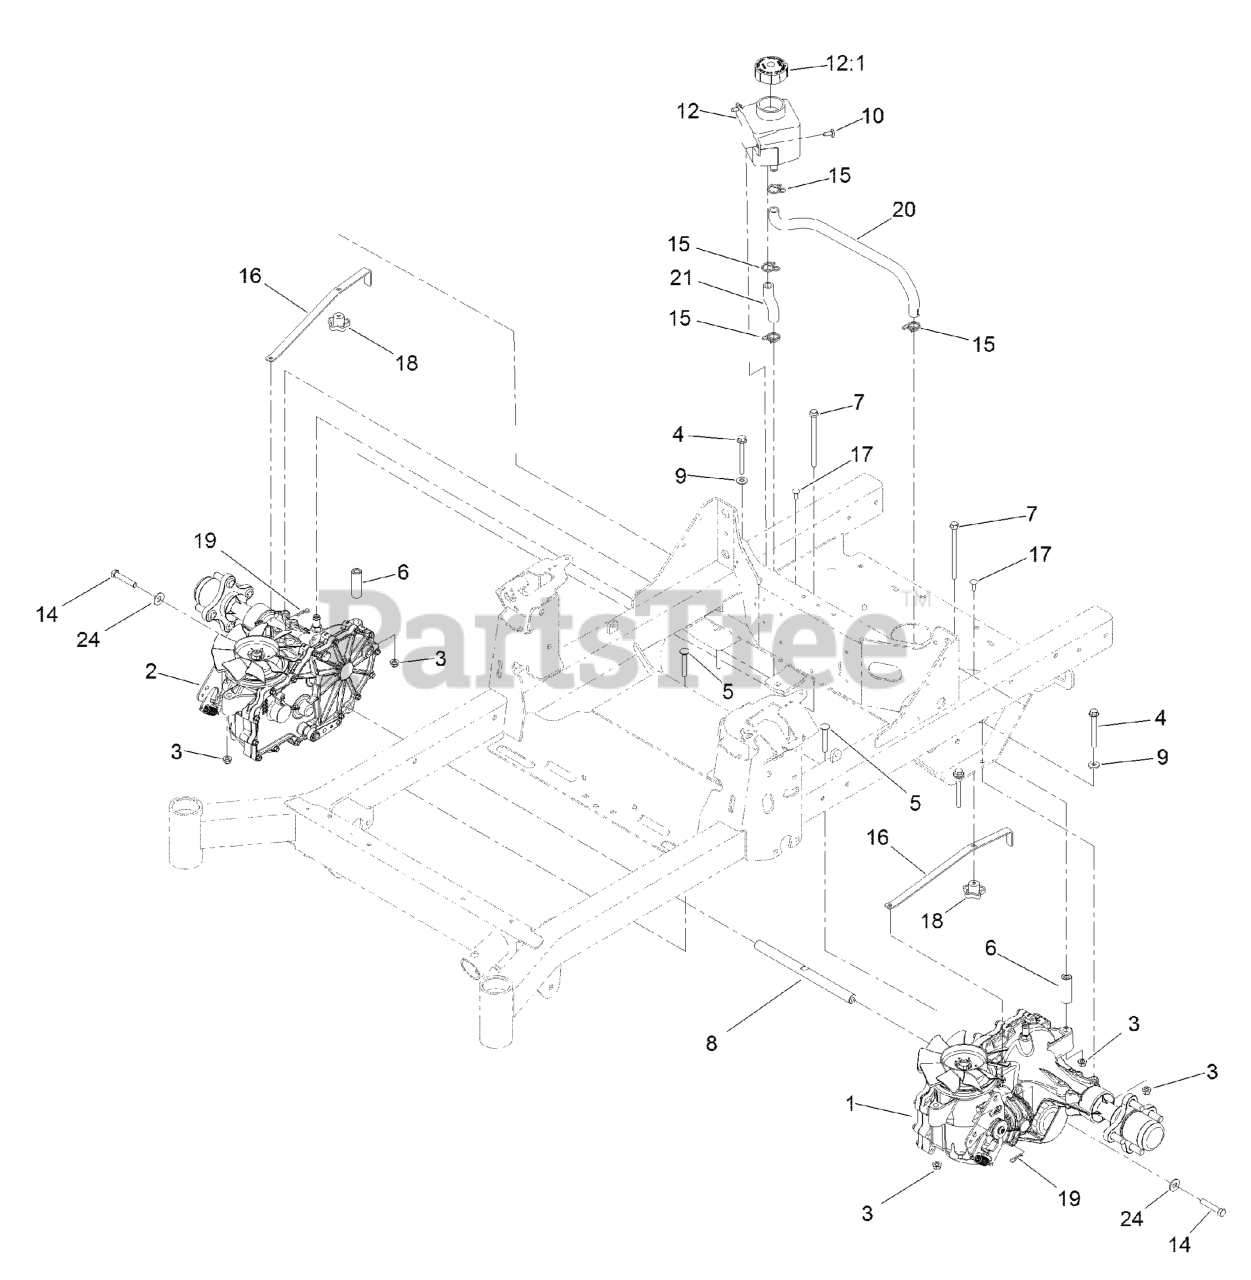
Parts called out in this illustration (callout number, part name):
1	LH TRANSAXLE ASM
2	RH TRANSAXLE ASM
3	NUT-HF, NI
4	SCREW-HHF
5	BOLT-CARR
6	SPACER-HYDRO
7	SCREW HHF
8	SHAFT-SPACER
9	WASHER-SPRING
10	SCREW-TORX
12	TANK-HYD
12:1	CAP-RESERVOIR, HYD
14	SCREW-HH W/LOCTITE
15	CLAMP-HOSE
16	ARM-BYPASS, HYDRO
17	BOLT-CARR
18	KNOB-HANDLE
19	PIN-COTTER
20	HOSE-HYDRAULIC
21	HOSE-HYDRAULIC
24	WASHER-FLAT
